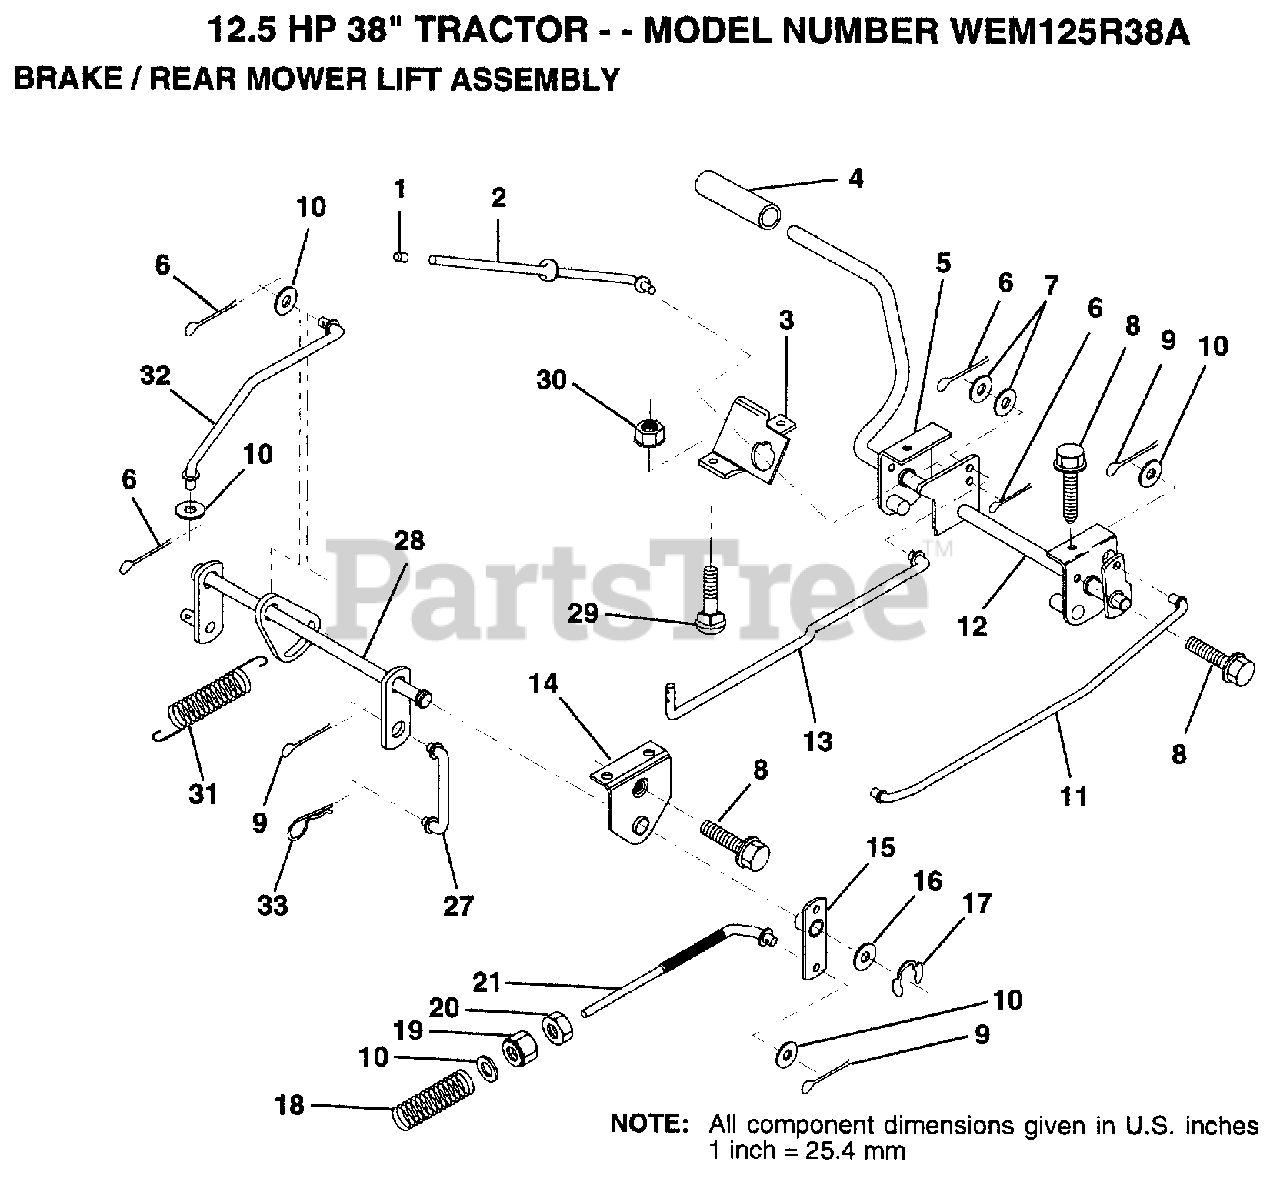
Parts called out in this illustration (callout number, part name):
2	"ROD,PARK BRAKE"
3	"BRKT,PARK BRAKE"
4	PEDAL COVER T
5	BRK ASM CLUT LH
7	WASHER
8	SCREW LT
9	COTTER PIN
10	WASHER
11	"ROD,FRT BRAKE"
12	PEDAL ASM CLU/BRK
13	"ROD,CLUTCH"
14	"BRKT,LIFT SHAFT"
15	PVT BRAKE ARM ASM
16	WASHER T
17	KLIP RING
18	SPRING ROD LT
19	NUT
20	NUT
27	LINK LIFT REAR LR
28	LIFT.ASM.REAR.LR
31	COUNTER SPRING
32	LINK LIFT LEVER
